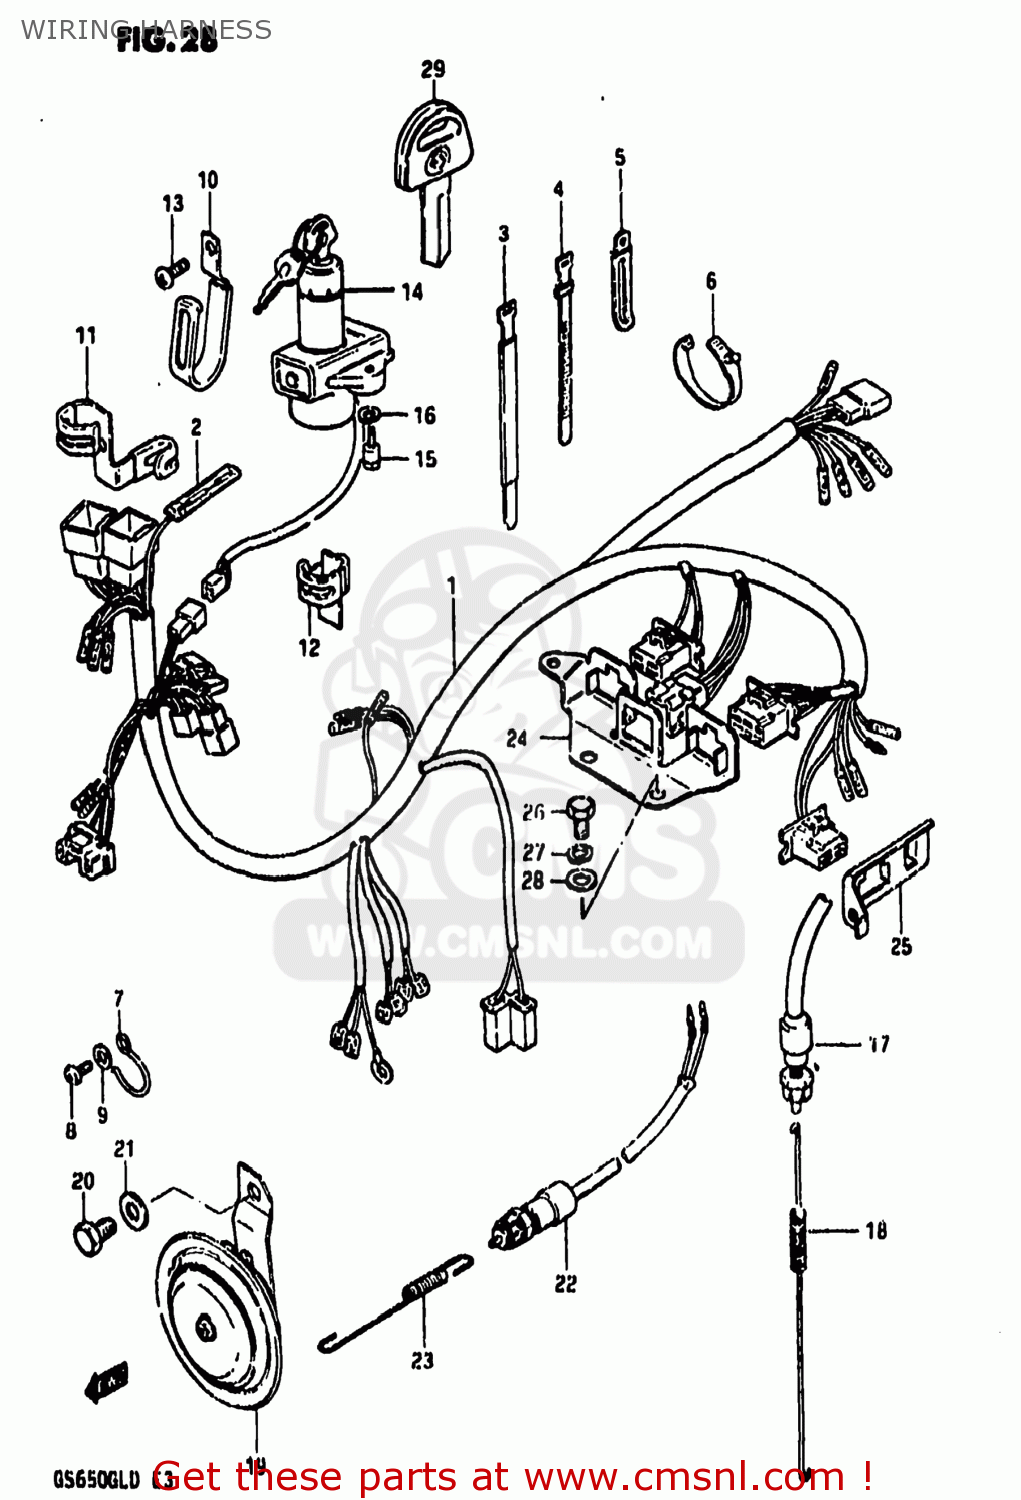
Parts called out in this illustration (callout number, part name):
1	HARNESS,WIRING
2	DIODE
3	CLAMP(L:250)
4	CLAMP
5	CLAMP
6	CLAMP,L:88
7	GUIDE,WIRING HARNESS
8	SCREW 6X12
9	WASHER
10	CLAMP,WIRING HARNESS
11	CLAMP,WIRING HARNESS
12	CLAMP,WIRING HARNESS
13	SCREW
14	SWITCH ASSY,IGNITION
15	BOLT
16	LOCK WASHER
17	SWITCH ASSEMBLY,STOP LAMP
18	SPRING
19	HORN ASSEMBLY
20	BOLT 8X12
21	WASHER
22	SWITCH ASSEMBLY,SIDE STAND
23	SPRING
24	PLATE, COUPLER HOLDER (A)
25	PLATE, COUPLER HOLDER (B)
26	BOLT
27	LOCK WASHER
28	WASHER
29	KEY,BLANK
